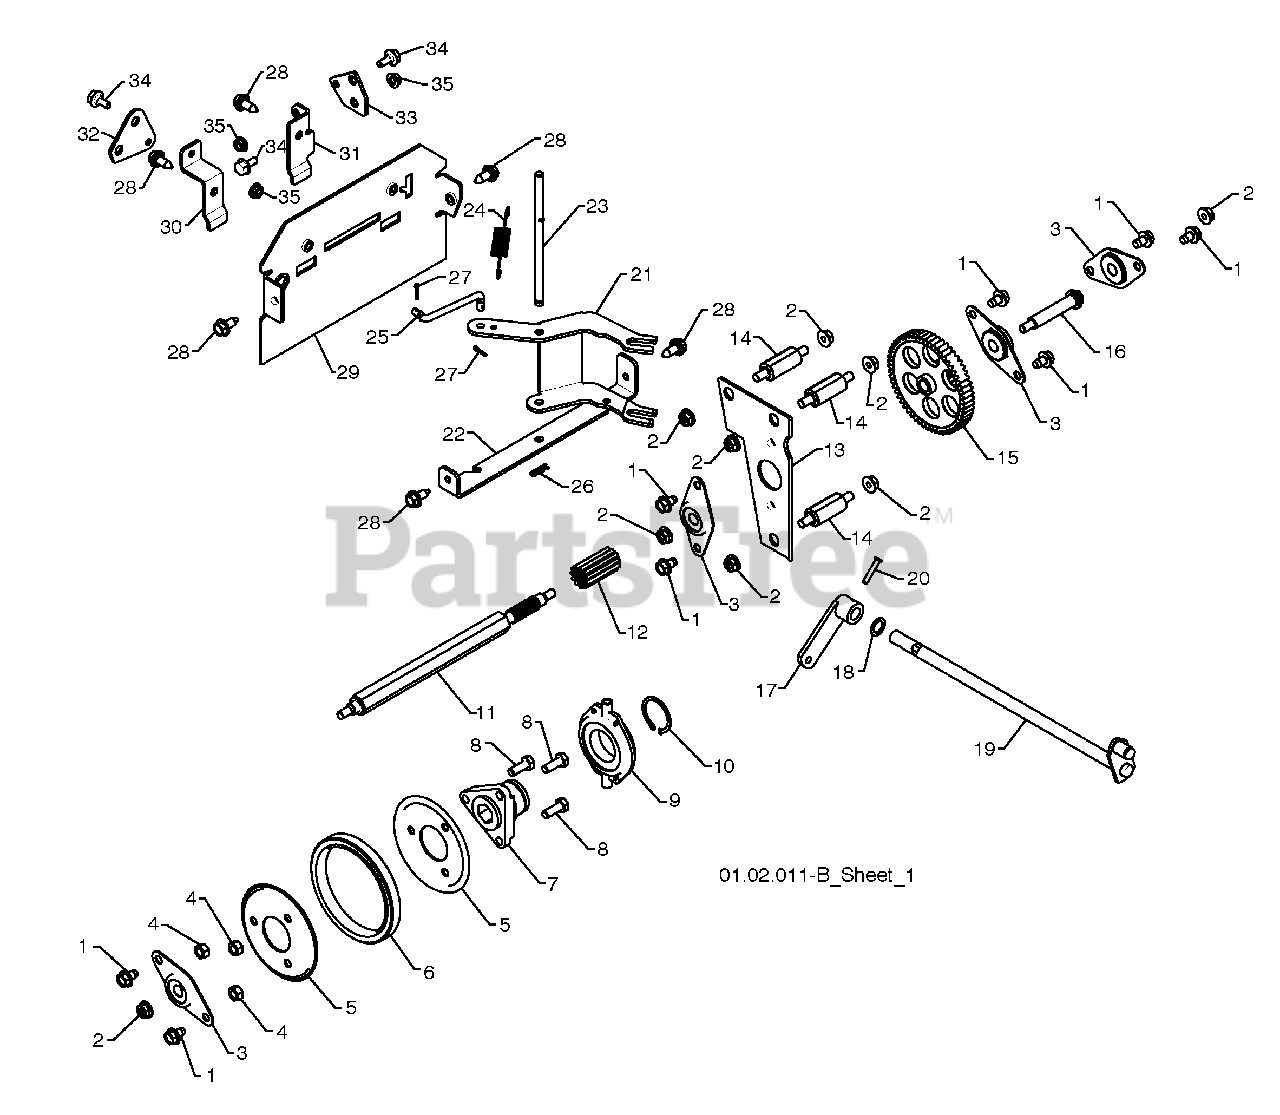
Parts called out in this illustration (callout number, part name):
1	BOLT 5/16-18 X .500
2	NUT 5/16-18
3	FLANGE BEARING
4	NUT 5/16-18
5	RUBBER WHEEL PLATE
6	RUBBER WHEEL RING
7	RUBBER WHEEL HUB
8	BOLT 5/16-18 X .875
9	TRUNNION BEARING ASSEMBLY
10	RETAINER
12	PINION GEAR
13	AUXILIARY PLATE
14	SPACER PLATE
15	INTERMEDIATE GEAR
16	AUXILIARY SHAFT
17	CONTROL ARM
19	CONTROL SHAFT ASSEMBLY
20	CLEVIS PIN
21	SHIFTER LEVER
22	PIVOT BRACKET
25	SHIFTER LINK
28	SCREW 5/16-18 x .750
29	REAR PLATE
30	SHIFTER PLATE BRACKET
31	CLUTCH PLATE BRACKET
32	SHIFTER PLATE
33	CLUTCH PLATE
34	SHOULDER BOLT 1/4-20 X .500
35	NUT 1/4-20
